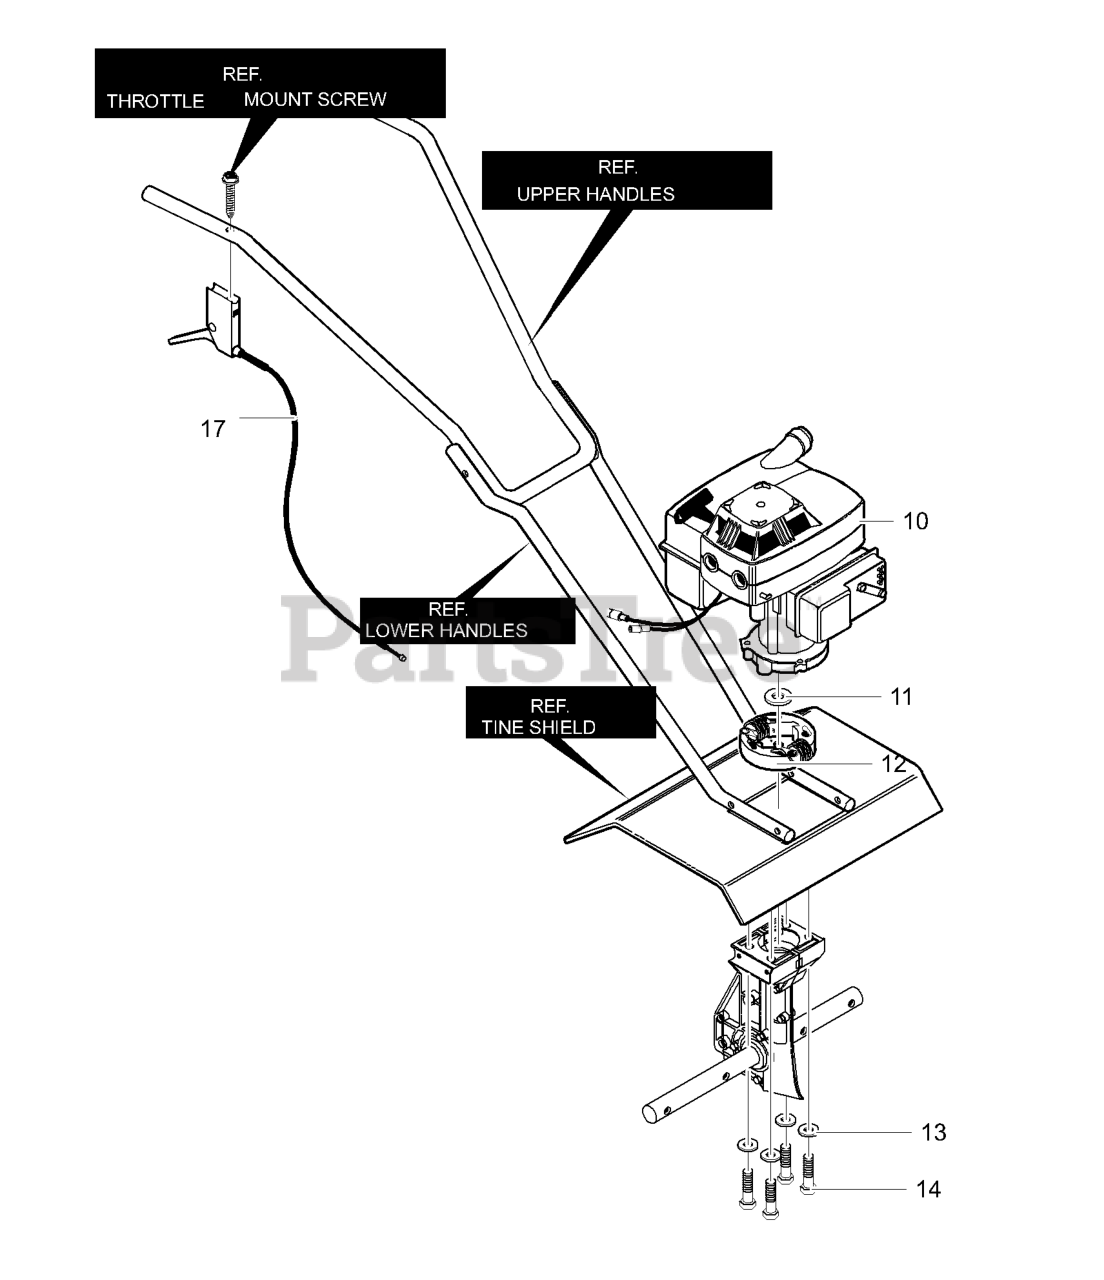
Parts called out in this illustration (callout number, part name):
10	Engine
11	Flat washer
13	Washer, Regsptlk
14	Screw
17	Cable, Throttle
